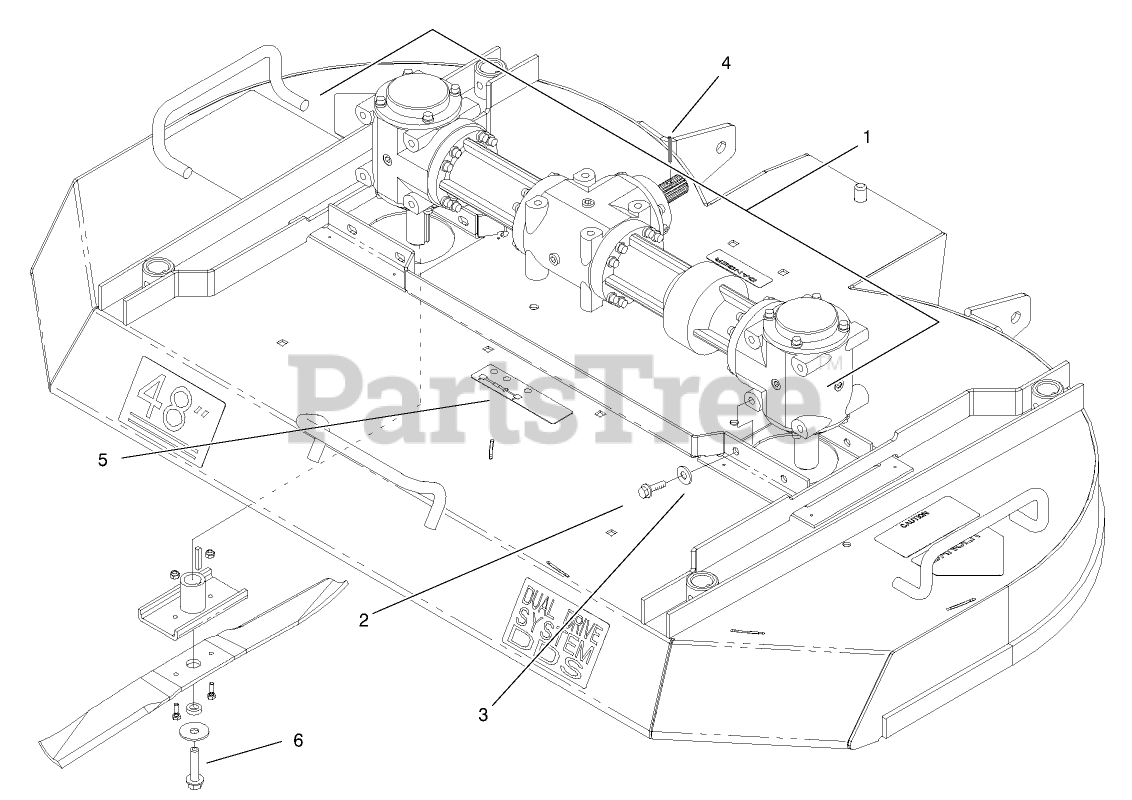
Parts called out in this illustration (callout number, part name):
1	Gearbox ASM
2	SCREW-HSH
3	WASHER
4	PIN-SPRING
5	Decal-Transmission Fluid (only on: 105-6172)
5	Decal-Gearbox Lube, Ofz (only on: 105-6178)
6	BOLT-BLADE, LH THREAD
